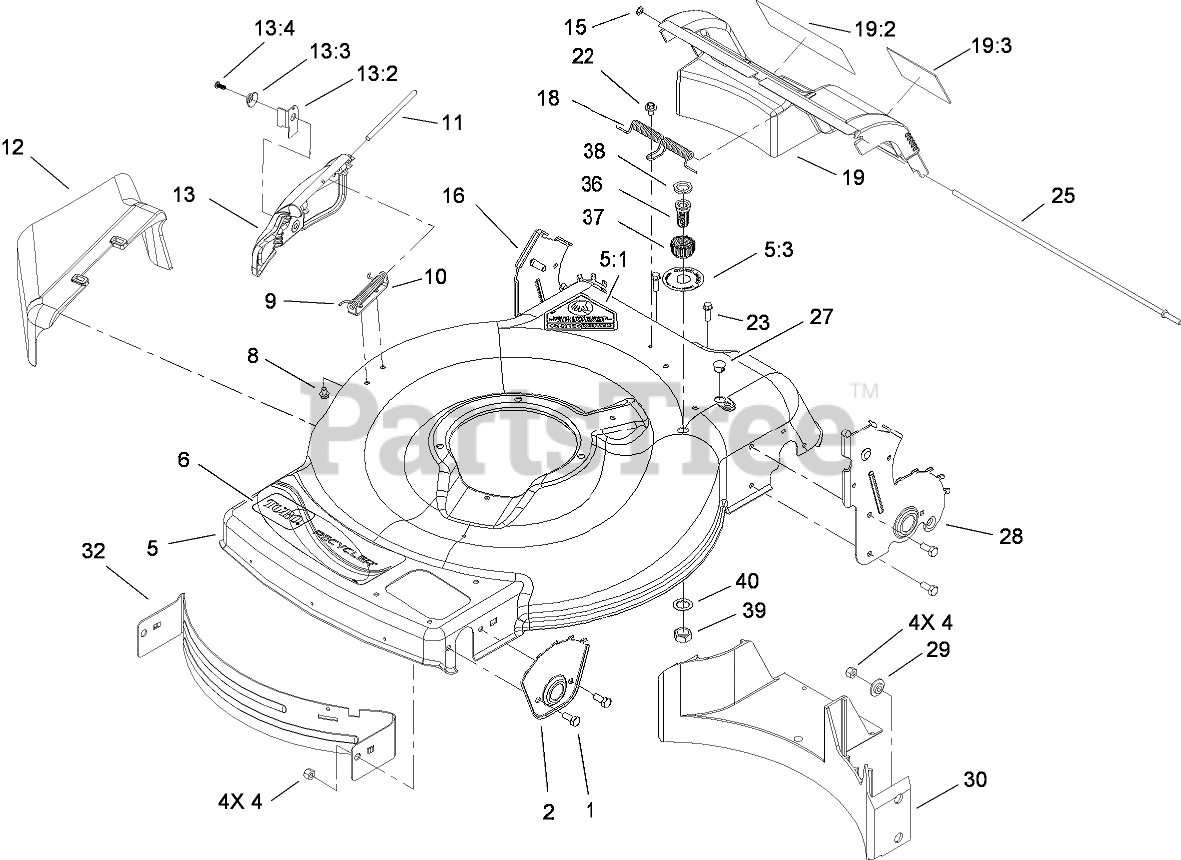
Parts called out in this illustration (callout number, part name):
1	SCREW-HH
2	Plate-HOC, Front
4	NUT-LOCK, NI
5	HOUSING ASM
5:1	DECAL-DANGER
5:3	DECAL-PORT, WASHOUT
6	DECAL-RECYCLER (RWD)
8	SCREW-HWH
9	SPRING-TORSION
10	BRACKET-COVER
11	ROD-COVER
12	CHUTE-DISCHARGE, SIDE
13	DISCHARGE DOOR ASM
13:2	LATCH-DOOR
13:3	CAP-DOOR
13:4	SCREW-PLASTITE
15	NUT-PUSH
16	8 INCH RH HOC PLATE ASM
18	Spring-Door, Rear
19	REAR DOOR ASM
19:2	DECAL-WARNING
19:3	DECAL-WARNING
22	SCREW AND WASHER ASM
23	SCREW-HWH
25	Rod-Pivot, Rear Door
27	Plug-Dome
28	8 INCH LH HOC PLATE ASM
29	Washer-Stepped
30	Baffle-Rear
32	BAFFLE-FRONT
36	PORT-WASHOUT
37	COUPLING-HOSE, WASHOUT PORT
38	WASHER-SEAL, WASHOUT PORT
39	NUT-JAM
40	WASHER-TOOTH, INTERNAL
